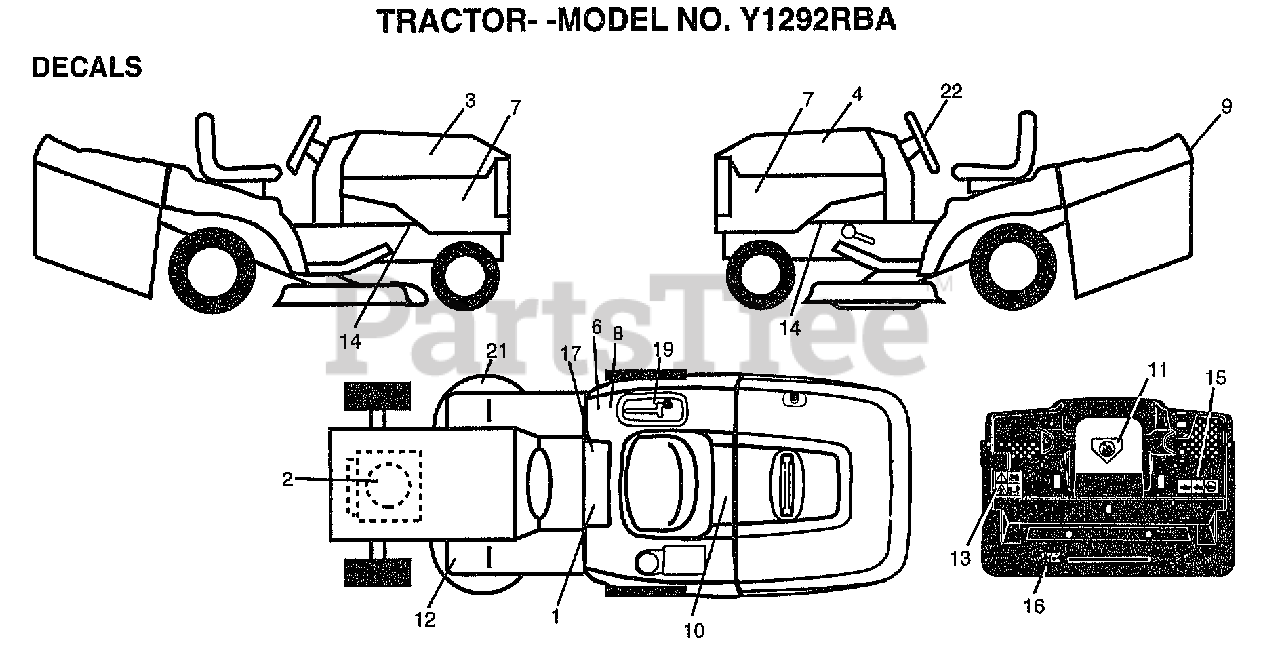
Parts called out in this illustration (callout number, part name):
1	DECAL.READ.O.MANU
2	DECAL.ENGINE.B&S.12HP
3	DECAL.HD.RH.
4	DECAL.HD.LH.
7	DECAL, PANEL SIDE LOGO
8	DECAL.EURO.ST.CE.
10	DECAL.BATRY.3-3908
11	DECAL.DANGER.CUTF
12	DECAL-BRAKE/CLUTC
13	DECAL.WARNING.BACKPLATE.CRD
14	"DECAL CHASSIS,HOT"
15	DECAL, OPER BAG
16	DECAL.DRAWBAR.LDL
17	DECAL BRAK PARK
19	DECAL.CONSOLE.6SP.CRD
21	DECAL.DECK.HEX.BELT
22	DECAL.INS.STRG.WH
